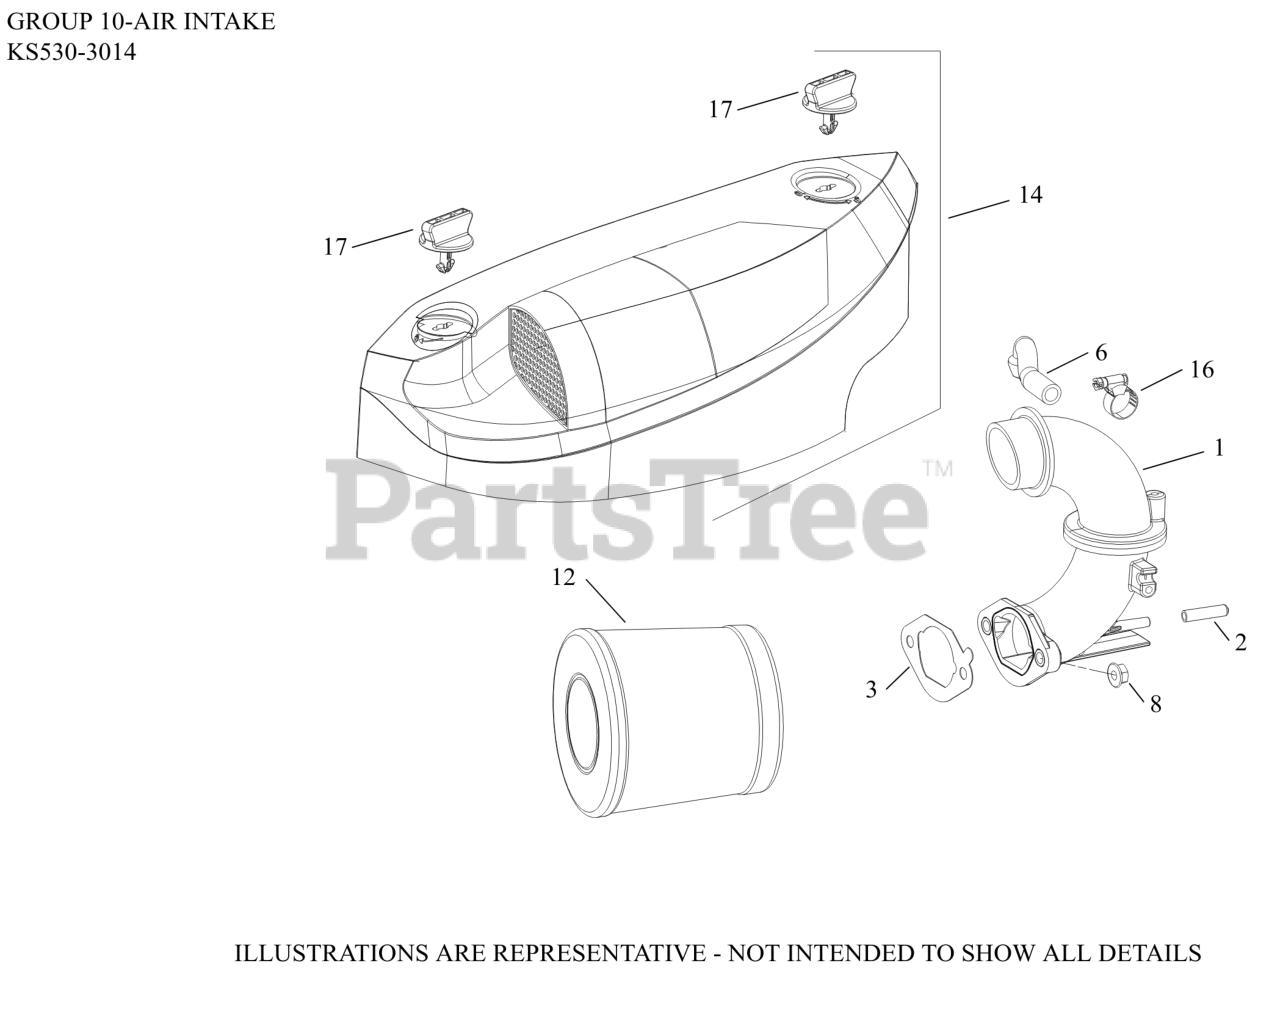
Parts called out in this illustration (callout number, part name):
1	ADAPTER, AIR CLEANER ASSY
2	CAP, MASKING
3	GASKET, CARBURETOR
6	HOSE, BREATHER
8	NUT, FLG M6X1.0
12	ELEMENT, AIR FILTER
14	ASSEMBLY, COVER AIR CLEANER (HOP)
16	CLAMP, HOSE (KM)-USE 25 237 31-S
17	KNOB, AIR CLEANER COVER
